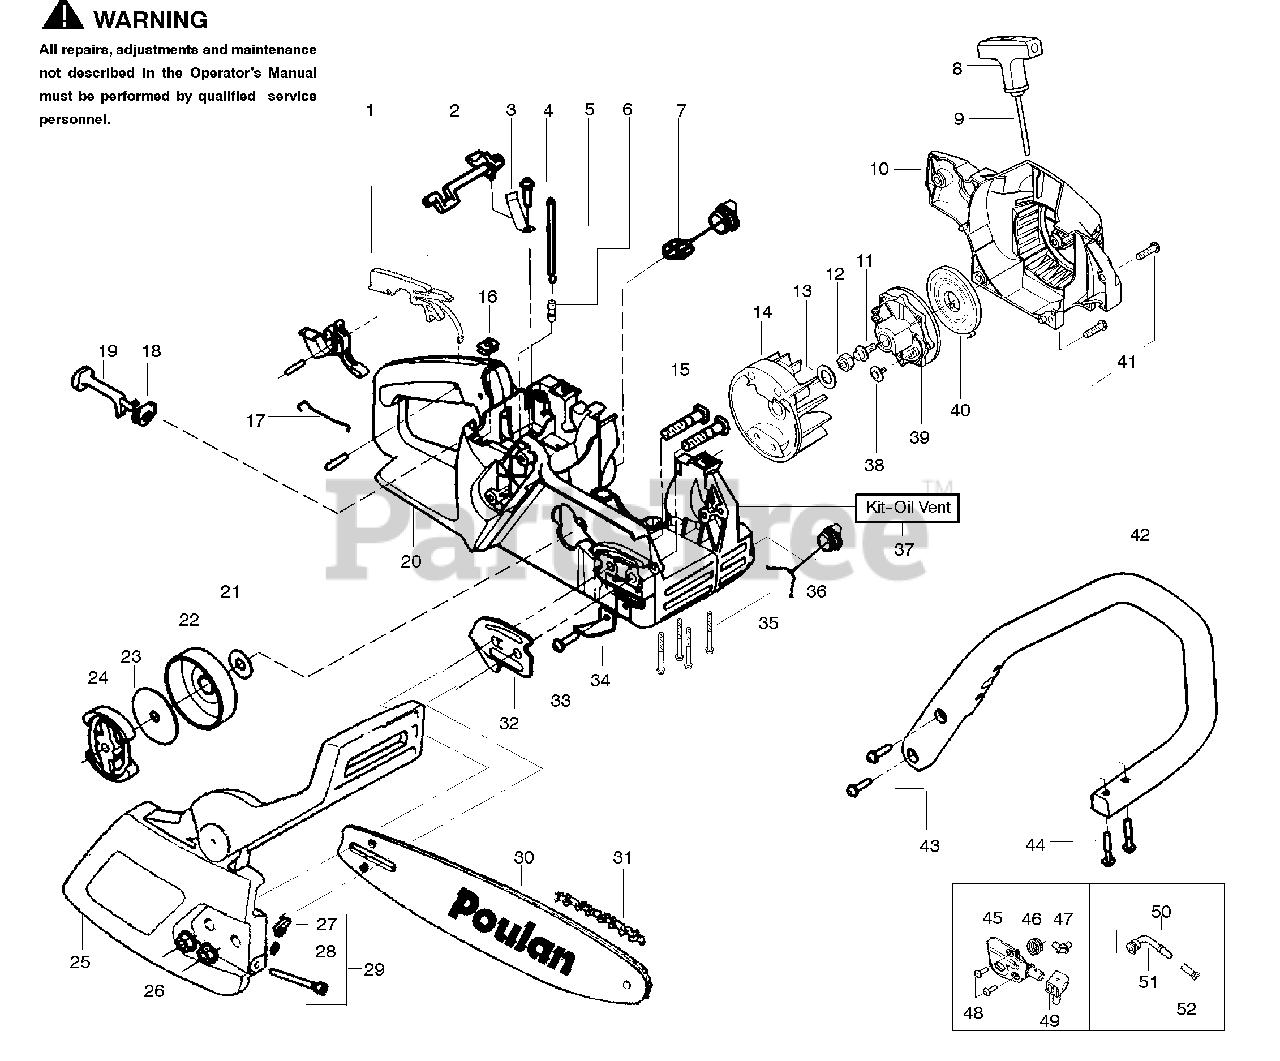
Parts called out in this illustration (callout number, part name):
1	Kit-Trigger & Lockout
2	Lever-Switch
3	Spring-Switch
5	Kit-Fuel Line (Large)
7	Assy-Fuel Cap
8	Handle-Starter
13	Washer-Flywheel
14	Assy-Flywheel
15	Bolt-Bar Mounting
17	Wire-Throttle
18	Grommet-Choke Knob
20	Assy-Chassis
21	Washer - Thrust
22	Assy-Drum W/brg.
23	Washer-Clutch
24	Assy. - Clutch
25	Assy-Chain Brake
26	Nut-Bar Mounting
27	Pin-Bar Adjust
28	Retainer-Bar Adjust
29	Kit-Bar Adjust
31	Chain- 16"
32	Plate-Bar Mounting
34	Chain Catcher
39	Pulley-Starter
40	Spring-Starter
42	Handle-Front
45	Kit-Oil Pump
46	Gear-Worm Spring
47	Elbow-Oil Pickup
50	Assy-Oil-Pickup
